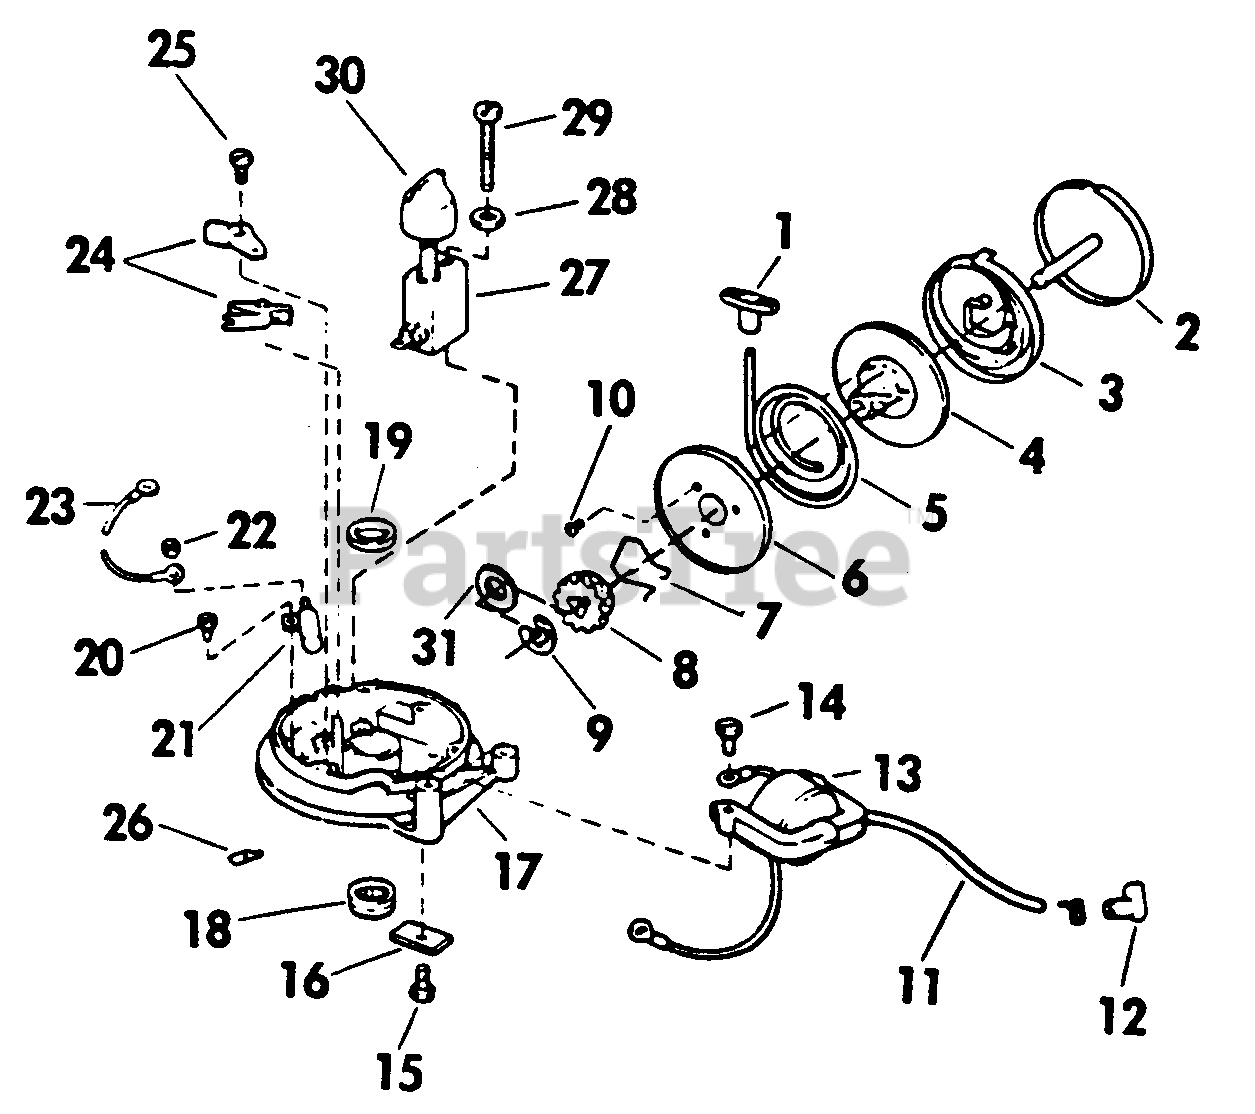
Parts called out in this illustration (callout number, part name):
1	Handle-Starter
2	Spring-Cup Pin Assy.
3	Spring-Starter
4	Pulley-Starter
5	Rope-Starter
6	Plate-Starter Pulley
7	Spring-Starter Pinion
8	Pinion-Starter
9	Retainer-Push-On
10	Scr. Threaded Cutting Starter
11	High Tension Lead Assy.
12	Cover & Terminal Assy.
13	Coil & Lamination Assy.
14	Scr.-Lamination Mtg.
15	Scr.-Starter Attach.
16	Clamp-Starter Pin
17	Arm. Pl., Brg. & Oil Seal Assy.
18	Bearing
19	Oil Seal
21	Cond. & Nut Assy.
23	Terminal & Lead Assy.
24	Brkr. Base & Arm Assy.
25	Screw-Breaker Base
27	Shorting Switch
